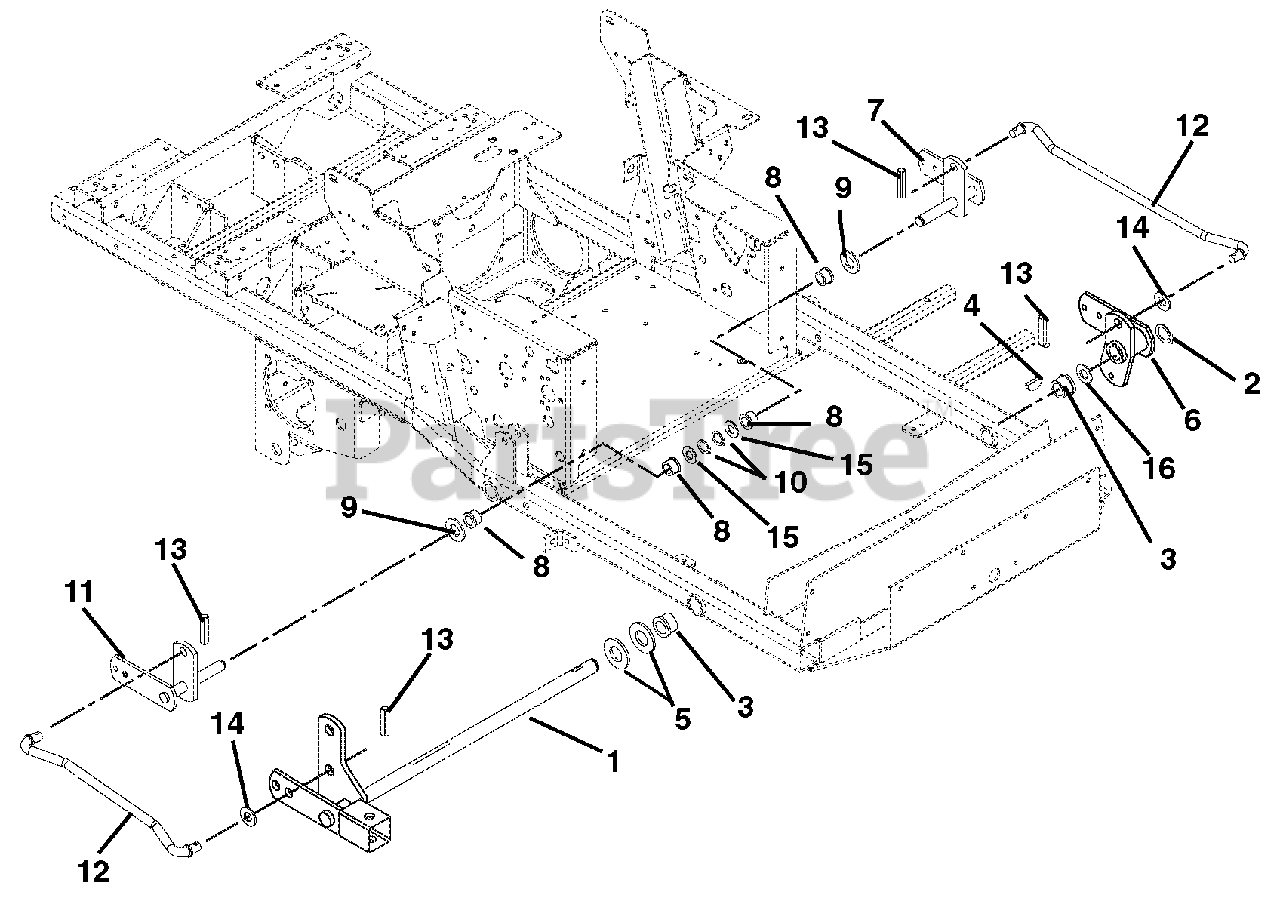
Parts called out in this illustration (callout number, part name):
1	Lift, Mower
2	Ring, Retaining External 1.00 x .078
3	Bushing 1.00 ID x 1.125 OD x 1.50
4	Key, Woodruff .25 x 1.00
5	Bushing 1.00 ID x 1.125 OD x 1.50
6	Weldment, Lift Arm - Front
7	Weldment, Rear Lift Arm – Left Hand
8	Bushing, Flange Nylon .762 x 1.0 x .58 x 1.48
9	Washer, Hardened Steel .758 x 1.23 x .031
10	Ring, Retaining External .689 x .077
11	Weldment, Rear Lift Arm – Right Hand
12	Rod, Lift Assist 19.35"
13	Pin, Roll .25 x 1.25 Stainless Steel
14	Washer, Flat Steel .630 x 1.25 x .062
15	Washer, Flat Steel .755 x 1.25 x .125
16	Washer, Hardened Thrust 1.00 x 1.55 x .03
